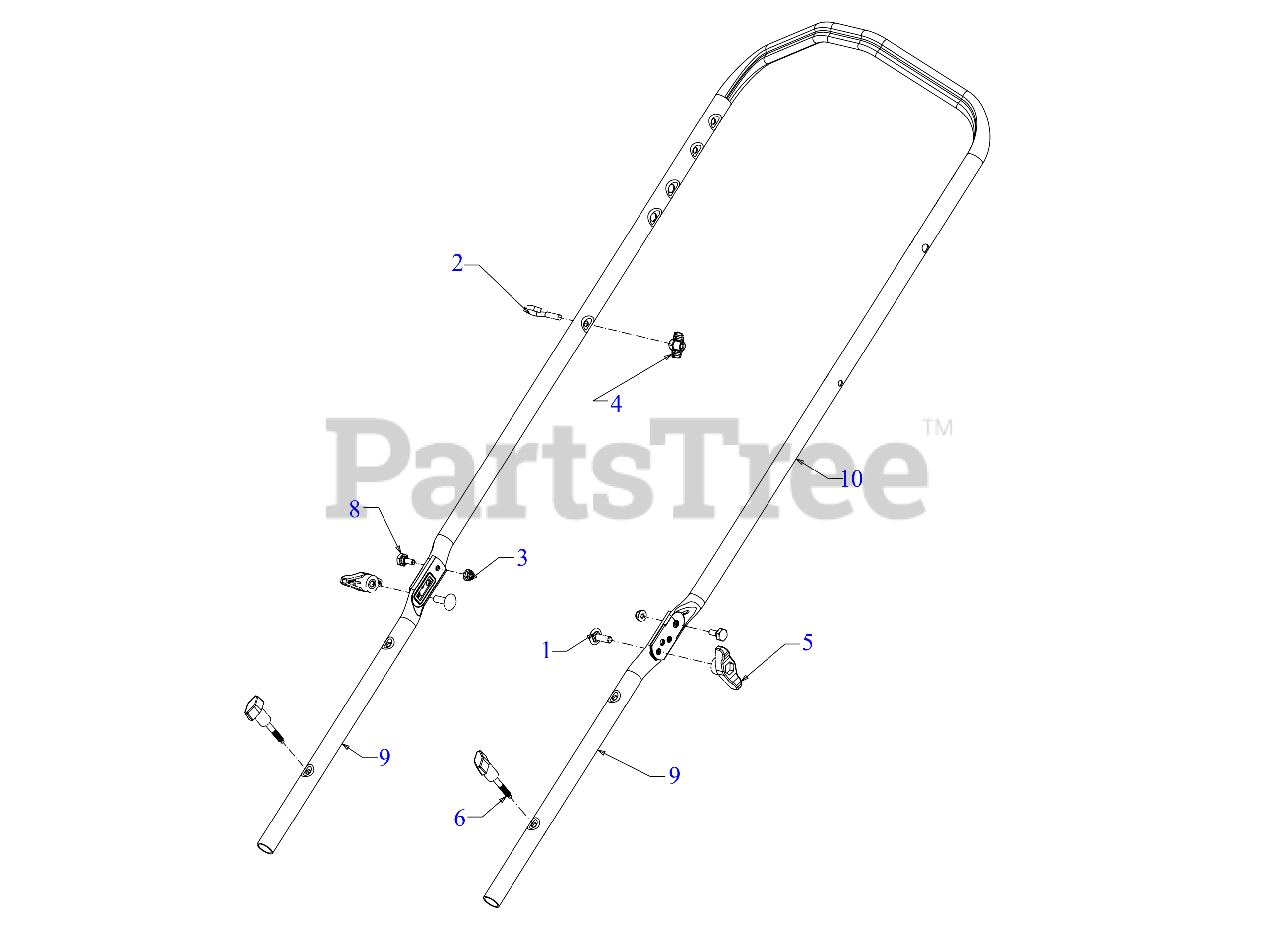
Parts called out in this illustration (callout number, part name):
1	SCREW 5/16-18 x 1.00 GR5
2	EYEBOLT 1/4-20
3	FLANGE LOCK NUT
4	HANDLE KNOB
5	WING KNOB 5/16-18
6	WING KNOB 1/4-20
8	SHOULDER SCREW
9	LOWER HANDLE (POWDER BLACK)
10	ERGO UPPER HANDLE
